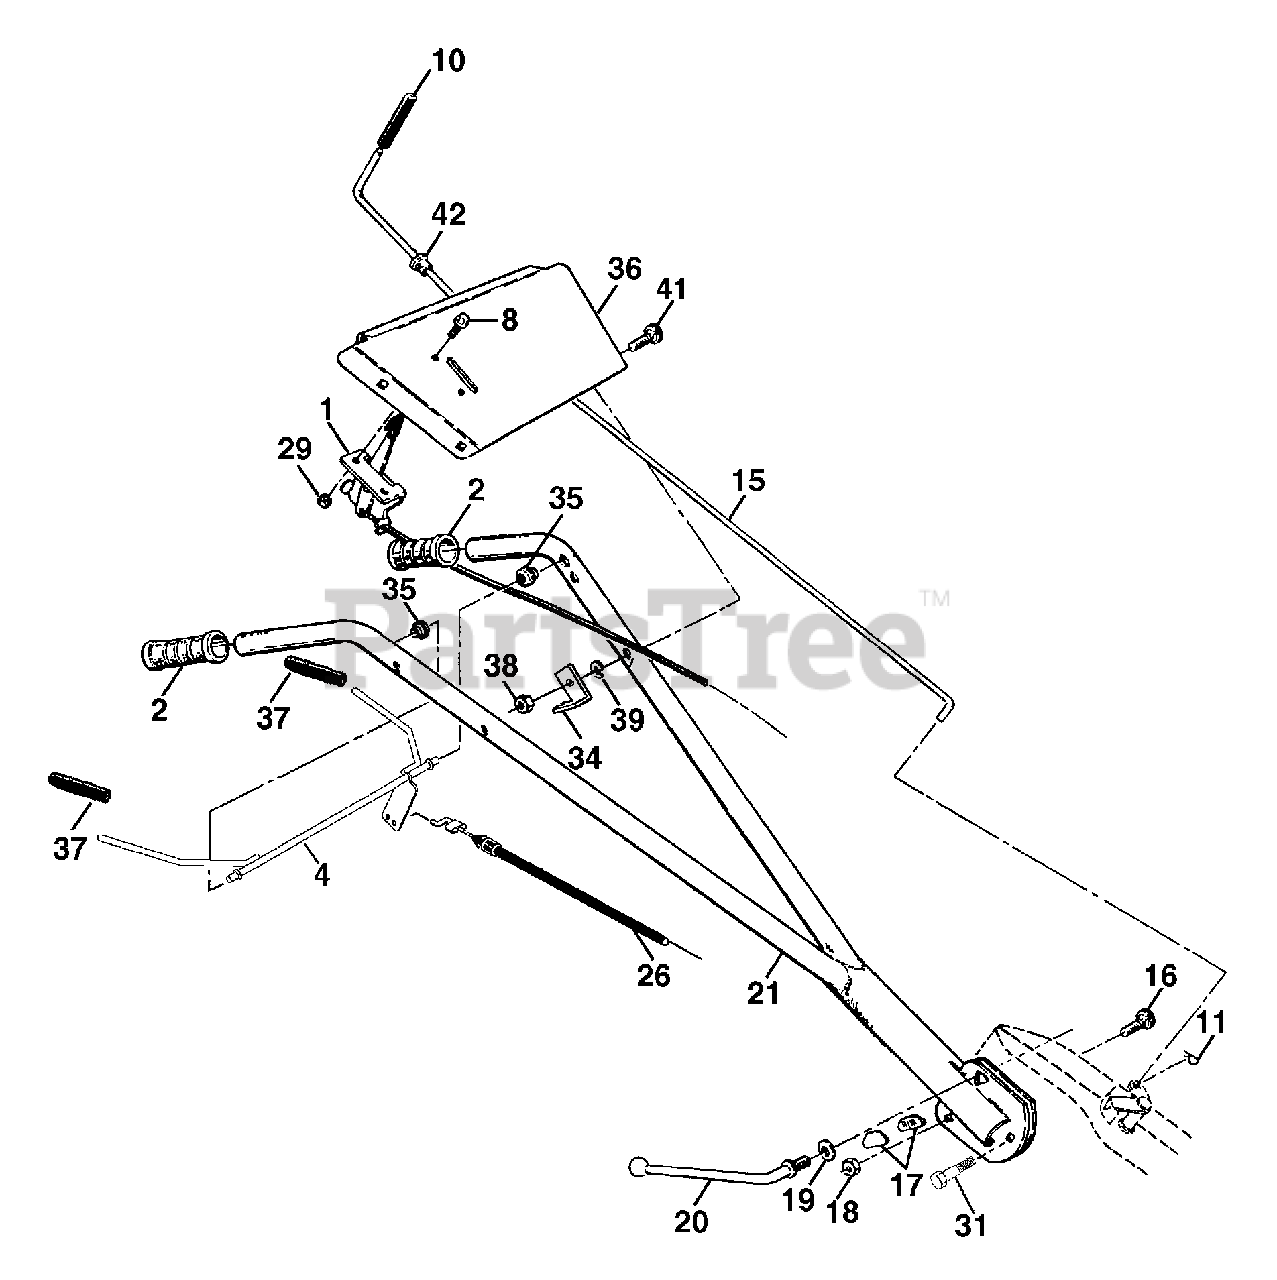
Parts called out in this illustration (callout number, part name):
1	Control, Throttle
2	Grip, Handle
4	Bar, Control
8	Screw, Pan Hd. #10-24
10	Grip, Handle
11	Clip, Hairpin
15	Rod, Shift
16	Bolt, Carriage 3/8-16 x 1 Gr. 5
17	Lock, Handle
18	Nut Crownlock 3/8-16 UNC
19	Washer 13/32 x 1 x 11 Ga.
20	Lever, Lock, Handle
26	Cable, Clutch
29	Nut, Keps #10-24 UNC
31	Bolt, Pivot
34	Bracket, Clutch Cable
35	Grommet, Handle
36	Bracket, Handle
37	Grip, Bar Control
38	Locknut 5/16-18
39	Washer, Lock 5/16
41	Bolt, Carriage 5/16-18 x 1-3/4
42	Bushing, Snap
